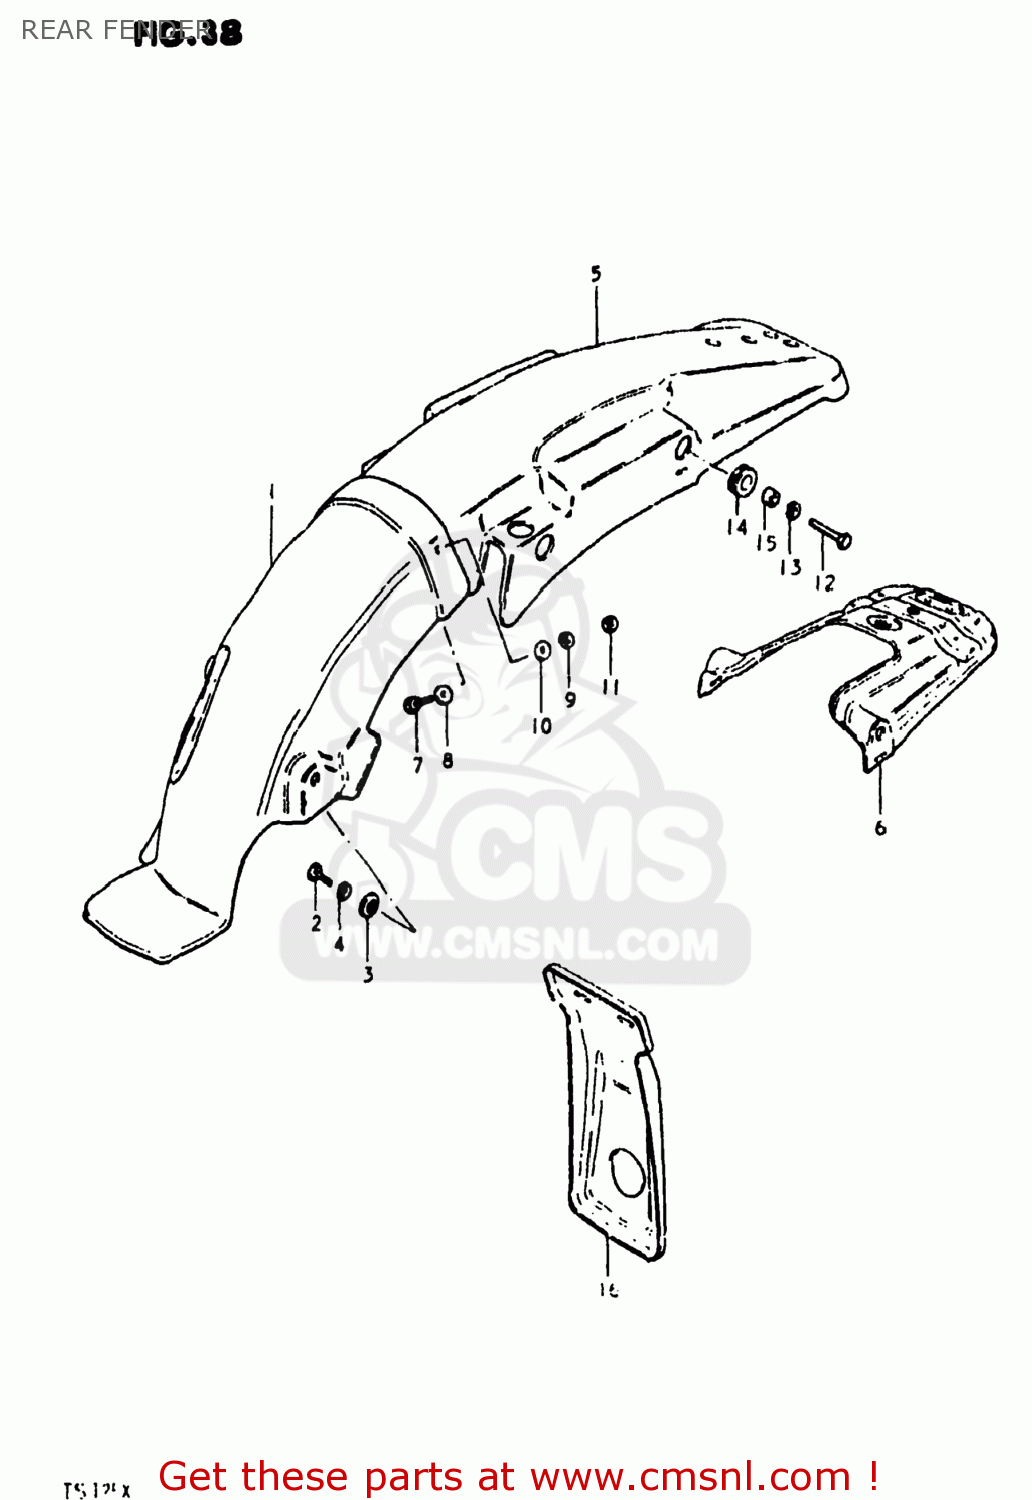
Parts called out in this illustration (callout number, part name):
1	BODY,REAR FENDER,FRONT
2	BOLT, UPPER
3	WASHER
4	LOCK WASHER
5	BODY,REAR FENDER,REAR
6	REINFORCEMENT,RR FENDER
7	BOLT
8	WASHER (5.5X16X1.2)
9	LOCK WASHER
10	WASHER(5.2X16X1)
11	NUT
12	BOLT (8X30)
13	LOCK WASHER
14	CUSHION
15	SPACER (8.2X12X7.5)
16	FLAP,RR FENDER MUD
